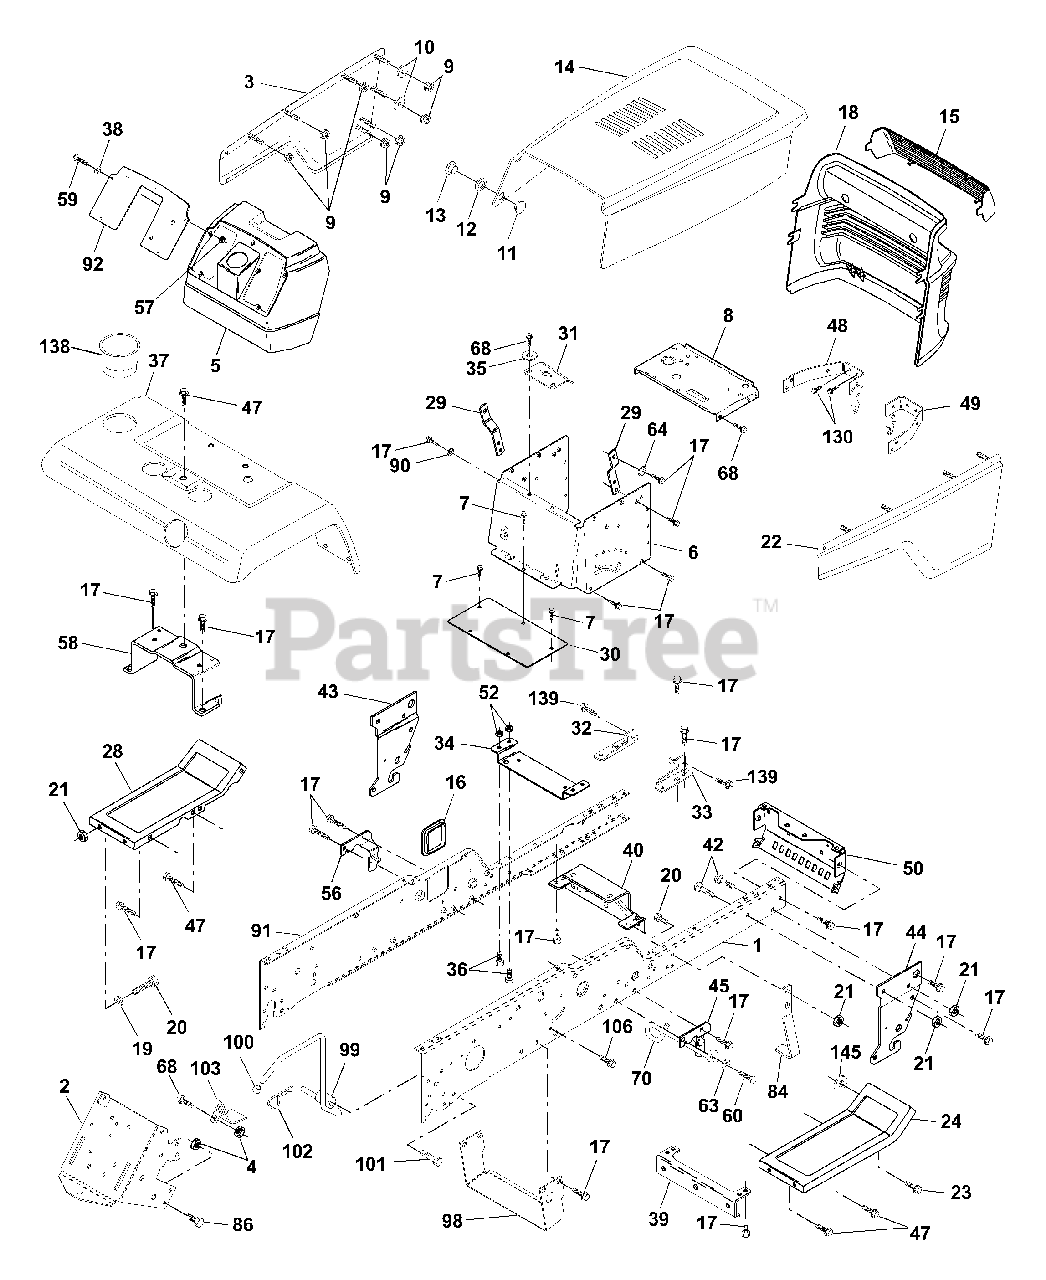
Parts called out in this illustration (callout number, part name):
1	Rail, Frame RH
2	Drawbar, Gt
3	Panel Asm., Side LH
4	Nut, Lock Hex 7/16 Unc
5	Dash, Plastic
6	Dash, 1PCS, Lower
7	Screw, Thd Cut 1/4-20 x 1/2
8	Support, Battery
9	Nut, Pal
10	Washer 9/32 x 1-1/4 x 16
11	Rivet Ratchet Male
12	Washer Nylon
13	Rivet Ratchet Female
14	Hood Asm., Pnt
15	Lens, Headlight Bar
16	Cover, Access
17	Screw, 3/8-16 x 3/4
19	Washer 13/32 x 13/16 x 12 Ga.
20	Bolt, Fin Hex 3/8-16 x 1
21	Nut, Crownlock 3/8-16
22	Panel Asm., Side RH
23	Screw 3/8-16 x 1-1/2
24	Footrest, RH
28	Footrest, LH
29	Bracket, Support Dash
30	Saddle
31	Bracket Supt 1-pc Vgt Steering
32	Bracket, Frame Pivot Lh
33	Bracket, Frame Pivot Rh
34	Bracket, Engine Support Rear
35	Washer 11/32 x 11/16 x 16 Ga.
36	Bolt, Fin Hex 5/16-18 x 3/4
38	Washer, Lock 1/4
39	Bracket, Axle Front
40	Bracket, Support Axle/Engine
42	Bolt Rdhd Sqnk 3/8-16 Unc x 1
43	Bracket, Spnsn Front Lh
44	Bracket, Spnsn Front Rh
45	Bracket Asm., Susp Chassis Rh
47	Screw Thdrol 3/8-16 x 1/2
48	Bracket Asm Hood Lh
49	Bracket Asm Hood Rh
50	Bracket, Chassis Front
52	Nut, Crownlock 5/16-18
56	Bracket Asm., Susp Chassis Lh
57	Nut Keps Blk Hex 1/4-20
58	Bracket Asm., Fender
59	Screw Mach Cr 1/4-20 x 3/4
60	Screw 3/8-16 x 1-1/4
63	Washer 13/32 x 1 x 14 Ga.
64	Washer Serrated Disc 13/32 x 1
68	Screw, 5/16-18 x 1/2
70	Guide, Belt Mid Span
84	Stop, Over Center Mower
86	Bolt, Fin Hex 7/16-14 Unc x 1
90	Washer, Lock External Tooth 3/8
91	Rail, Frame Lh
92	Plate, Silkscreen Dash
98	Bracket Chassis Skid
99	Rod Asm. Bypass
100	Cap By Pass Rod
101	Screw Thdrol. 3/8-16 x 1-3/4
102	Retainer Spring 1"
103	Bracket Lock Bypass
106	Screw Thdrol Hex Head Zinc
130	Screw Hw Hd Hi-Lo #13-16 x 3/4
138	Cupholder
139	Bolt Shoulder 5/16-18
145	Washer Flat 13/32 x 7/8 x 14 Ga.
155	Screw 3/8-16 x 3/4
